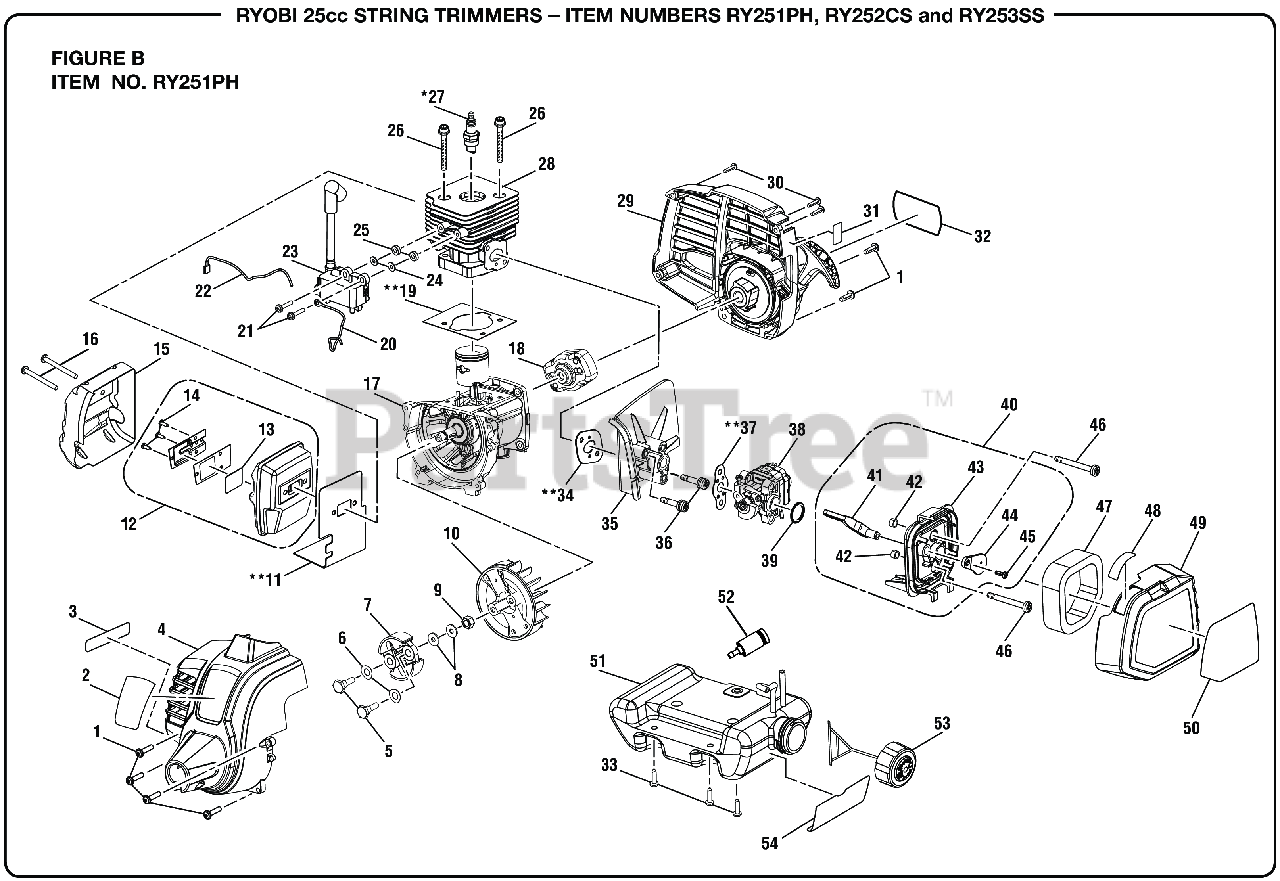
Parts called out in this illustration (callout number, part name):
1	Cap Screw w/Washer (M5 x 16 mm, T25 Torx Soc. Hd.)
2	Logo Label (Front)
3	Warning Label (Combustion)
4	Front Housing Assembly w/ Labels
5	Clutch Shoulder Bolt (M6 x 22.5 mm, Hex Hd.)
6	Washer (Curved)
7	Clutch Assembly
8	Washer (ID6 x OD15 x 1.2t)
9	Flange Nut (M8, Flywheel)
11	Muffler Gasket
12	Muffler Assembly
13	SCREEN
14	Screw (6-20 x 1/4 in., T20 Torx Pan Hd. S.T.)
15	HEAT SHIELD
16	Screw (M5 x 50 mm, Torx Slotted Recessed Pan Hd.)
17	Crankcase Assembly
18	Starter Cup
19	Gasket
20	Lead Wire Assembly, Red
21	Screw (M4 x 22 mm, T20 Torx Slotted Recessed Pan Hd.)
22	Lead Wire Assembly, Black
23	Coil Boot Assembly
24	Flat Washer (OD10 x ID42 x 1t)
25	Phenolic Spacer (Ignition Module)
26	Screw (M5 x 22 mm, T25 Torx Soc. Hd.)
27	Spark Plug (Champion RCJ6Y)
29	Screw (M4 x 18 mm, T20 Torx Pan Hd. S.T.)
30	Screw (M4 x 20 mm, T20 Torx Pan Hd. S.T.)
31	Primer Bulb Location Label
32	Shoulder Screw (M4 x 14 mm, T25 Torx Truss Hd.
33	Shoulder Screw w/Washer (M4 x 14 mm, T25 Torx Truss Hd.)
34	Heat Dam Insulator
35	Screw (M5 x 30 mm, T25 Torx Pan Hd. S.T.)
36	Screw w/Washers (M5 x 30 mm, T25 Torx Pan Hd.)
37	Gasket
38	Carburetor Assembly
39	Carburetor O-Ring
40	Airbox Base Assembly
41	Compression Limiters
42	Washer (ID5.8 x OD11.5 x 1.7t)
43	Air Box Base
44	Screw (M4 x 12 mm, T20 Torx Pan Hd. S.T.)
45	Screw (M4 x 12 mm, Slotted Recessed Pan Hd.)
46	Screw (M5 x 44 mm,T25 Torx Hd. Carburetor)
47	Air Filter (Element)
48	Choke Position Label
49	Airbox Cover (Inc. Key Nos. 48 & 50)
50	Starting Instructions Label
51	Fuel Tank and Cap Assembly
52	Fuel Filter
53	Fuel Cap Assembly
54	Fuel Mixture Label
